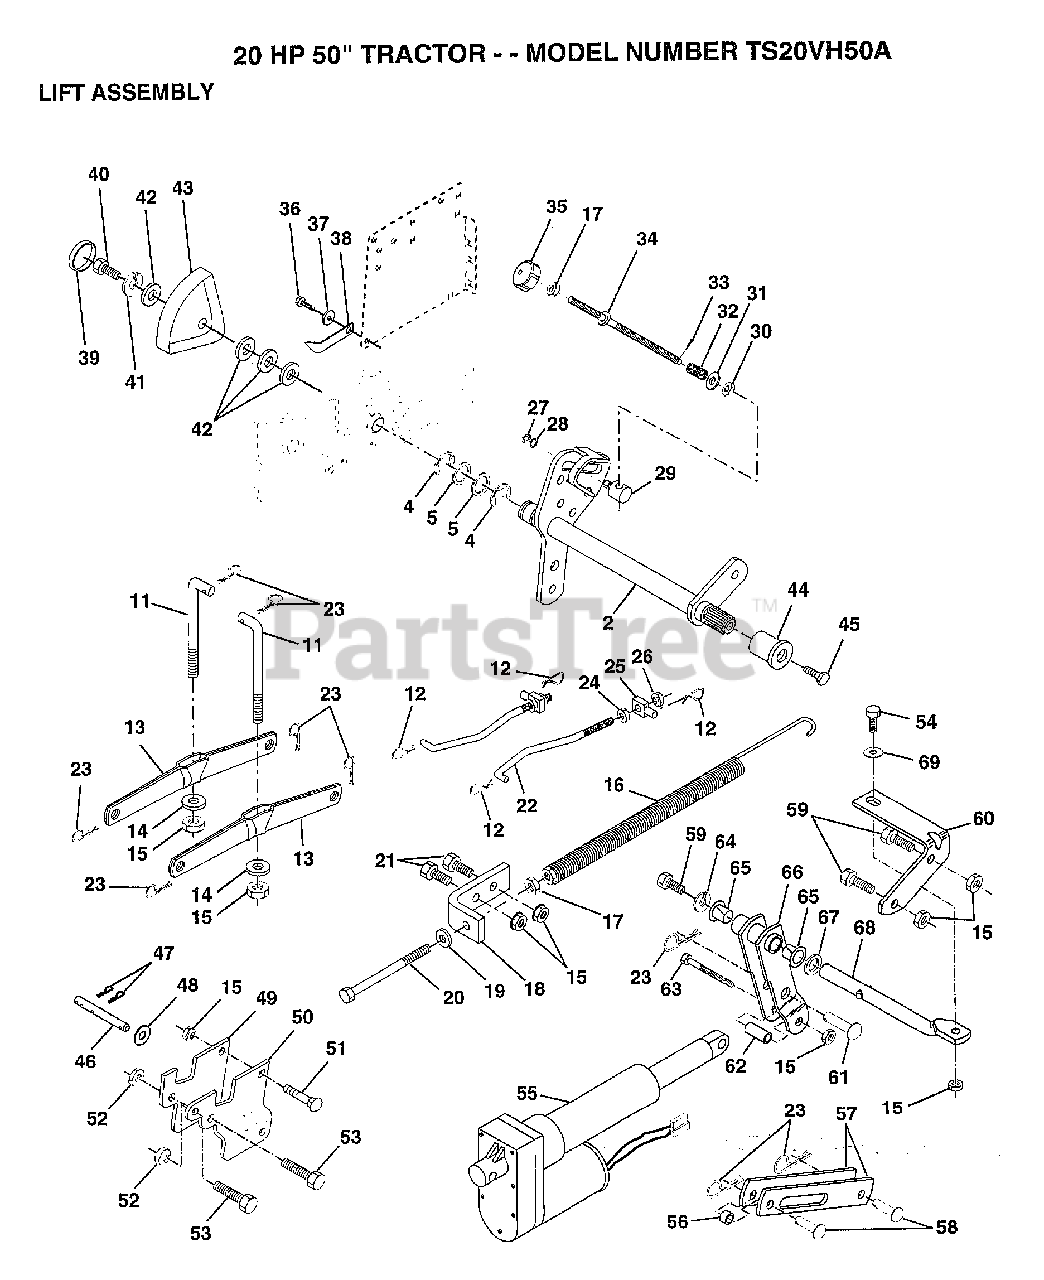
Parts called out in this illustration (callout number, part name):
4	E-RING
5	WASHER
12	RETAINER.SPRING
14	BEARING PVT LH
15	NUT
17	NUT
18	BRACKET SPRING AS
19	WASHER
20	BOLT-ADJ SPRING T
21	BOLT
22	LINK.FRONT
24	NUT
25	TRUNION
26	NUT.LK.W/WSH.1/2.
27	KLIP RING
28	WASHER
29	TRUNION LT
30	NUT T
31	WASHER
32	ROD.ADJ.LIFT
34	ROD.ADJ.LIFT
35	KNOB INF 3/8-16
36	SCREW
37	WASHER T
38	POINTER HGT IND
39	"PLUG,HOLE"
41	LOCKWASHER
42	WASHER
43	HEIGHT INDICATOR
44	LIFT HUB-LEVE T
45	BOLT
46	PIN.ACTUATOR
48	WASHER
49	BRACKET.ACTUAT.LH
50	BRACKET.ACTUAT.RH
51	BOLT
52	NUT.7/16
53	BOLT.HX.HD.7/16
55	ACTUATOR.07823175
56	SPACER.500X384X23
57	LINK.LIFT.ELECT.
58	PIN.PIVOT
60	BRACKET.ROD.PIVOT
61	PIN.PIVOT
62	TUBE GT
63	BOLT-HEX EAK
64	LOCKWASHER
65	NYLINER.ROD.PIVOT
66	ARM.ASM.PIVOT
67	WASHER
68	ROD.SUPPORT.PIVOT
69	WASHER
